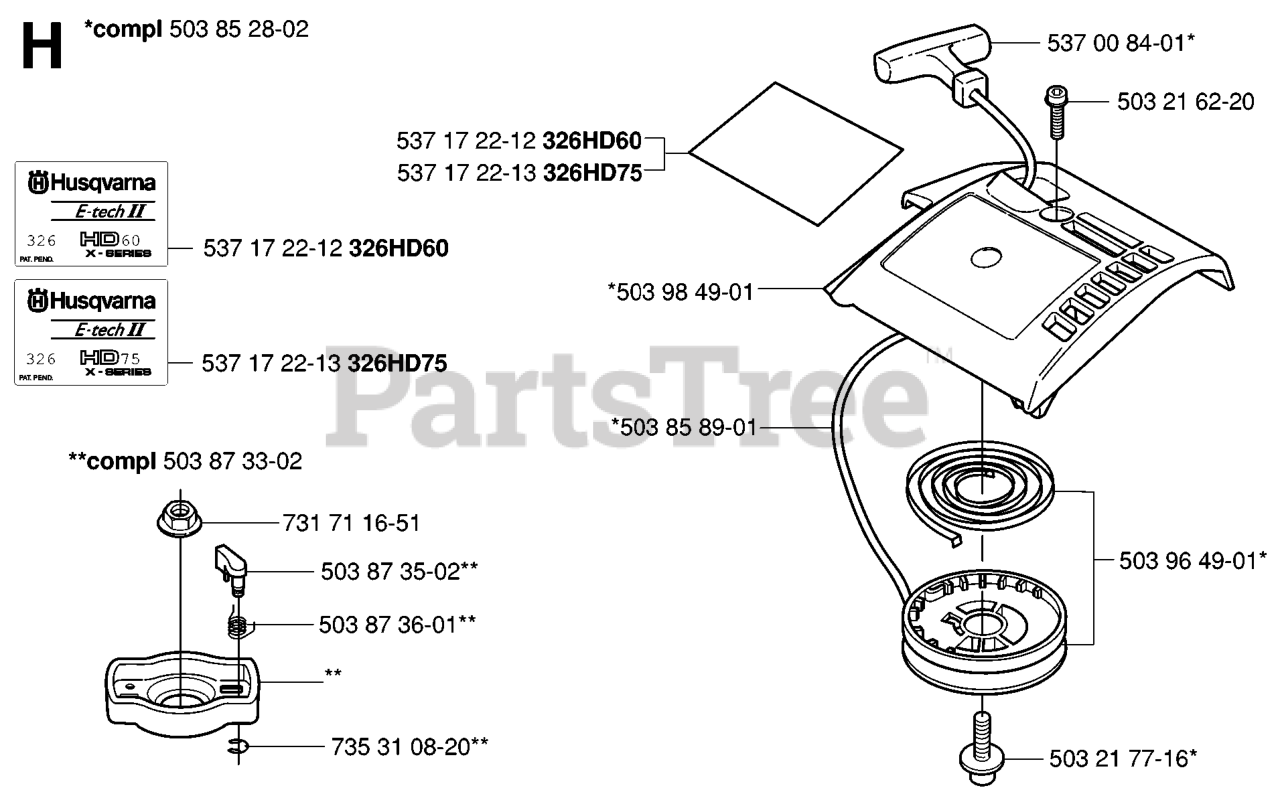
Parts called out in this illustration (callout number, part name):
1	STEERING WHEEL
2	AXLE ASSY
3	SPINDLE ASM LH
4	SPINDLE ASM RH
5	THRUST WASHER
9	BRNG T
10	DRAGLINK-STAMPED
11	WASHER, LOCK 3/8
13	BEARING AXLE
15	NUT-LOC,FLANGE LT
17	SHAFT ASM STEERING
18	THRUST WASHER
19	SHAFT,SUPPORT
20	WASHER
22	SCREW HEX SOCKET 1/4-20 X 5/8
23	SHAFT PITMAN
25	BRACKET STEERING
26	BUSHING.DRAGLINK (2 2)
27	GEAR.SECTOR
28	WASHER
29	SCREW
30	COTTER PIN
32	TIE ROD
36	BUSHING, STEERING
37	SCREW.TT.#10-32X.5.3/8.FLANGE
38	INSERT,STR WHEEL
39	WASHER T
40	GRIPCO NUT
41	ADAPTER LT
42	BOOT, STEERING
44	EXT SHAFT STEERING
46	CAP.SPINDLE.BLACK
47	ZERK M
51	NUT.71038.31-18.HEX.NYLOCK
54	BOLT.5/16-18X1-1/4 FULL.THREAD
62	KIT, STEERING ASSEMBLY
65	SPACER AXLE
66	BEARING ARM
67	Bolt, Hex 5/8 -11 x 2 - 3/4 Gr. 5
68	AXLE, BRACE
